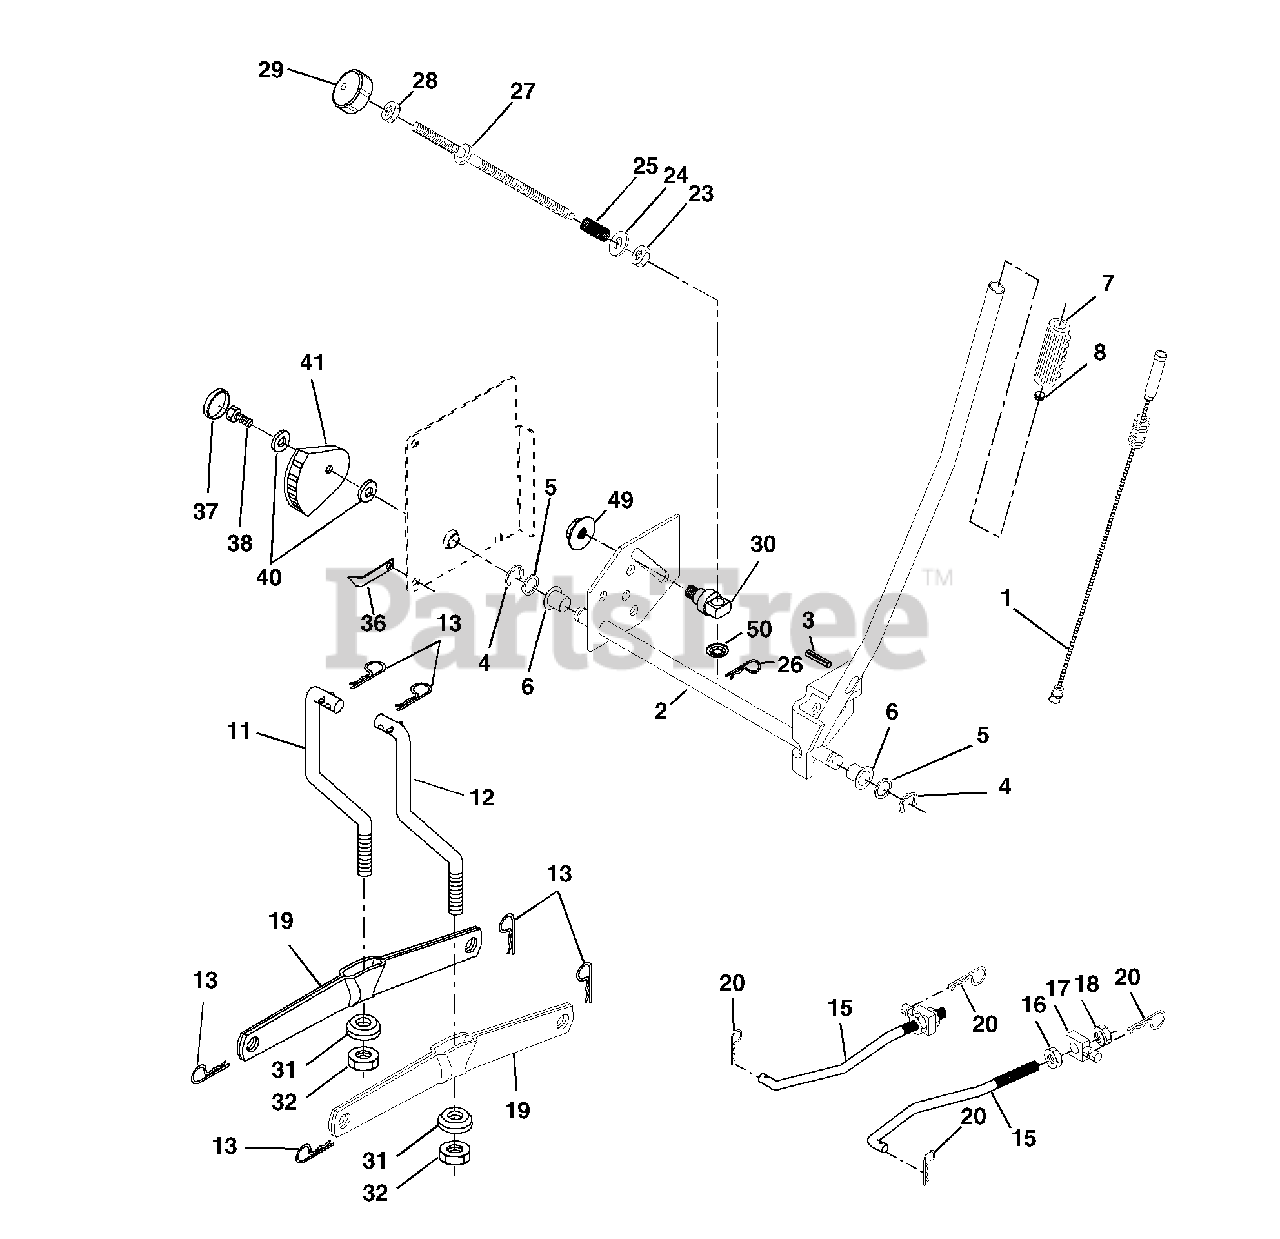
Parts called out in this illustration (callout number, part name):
1	Wire Asm Inner/Spring W/Plunger LT
2	Shaft Asm Lift RH w/Inf
3	Pin Groove 1 500 Zinc
4	E Ring #5133-62
5	Washer 21/32 X 1 X 21 Ga
6	Bearing Nylon Blk 629 Id
7	Grip Handle Fluted Blk
8	Button Plunger Black
11	Link Lift LH
12	Link Lift RH
13	Retainer Spring
15	Link Front
16	Nut Jam Hex 1/2-13 Unc
18	Nut Lock w/Wsh 1/2-13unc
19	Arm Suspension Rear
20	Retainer Spring
23	Nut Special
24	Washer 13/32 X 5/8 X 16 Ga
25	Spring 2-1/8"
26	Retainer Clip
27	Rod Adj Lift Zinc 7.49 Wrk Lg
28	Nut Hex Jam 3/8-16 Unc
29	Knob Inf 3/8-16 Unc Blk W/sym
30	Trunnion Infin Height
31	Bearing PVT Lift
32	Nut Crownlock 3/8-24
36	Indicator Height STLT
37	Plug Hole Blk 1.485/1.515 Dia.
38	Screw 5/16-18 x 1
40	Washer 11/32 x 1-1/2 10 Ga.
41	Scale Ind. Height Blk.
49	Nut Hex Flange Lock
50	Nut, Push Phos & Oil
